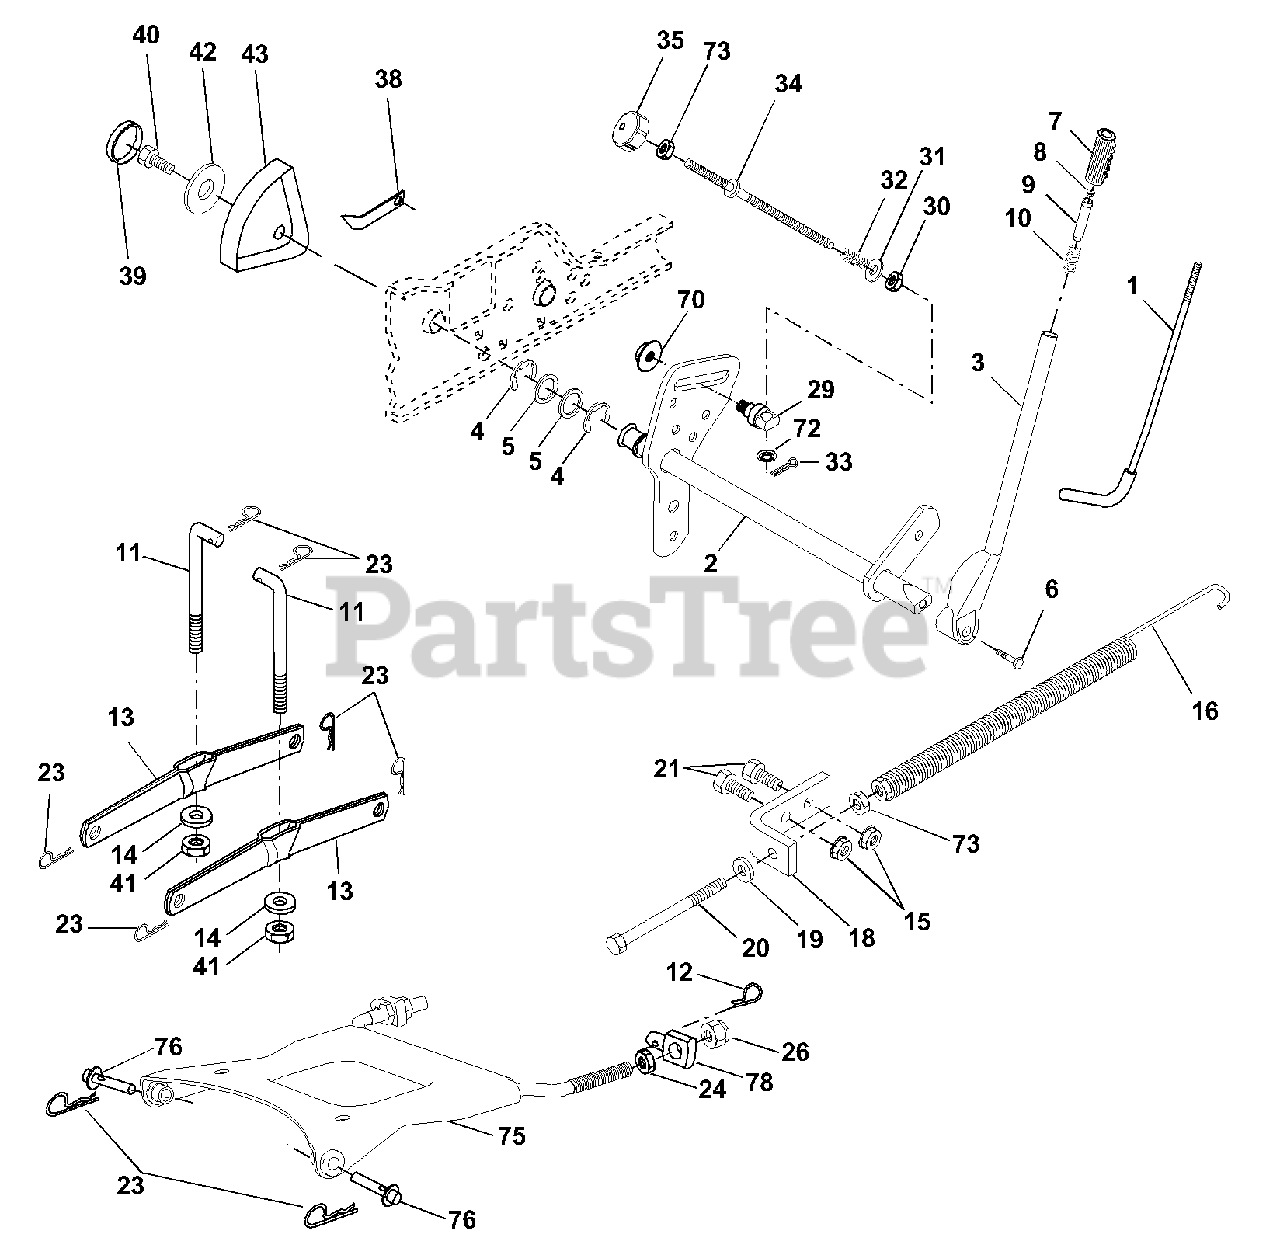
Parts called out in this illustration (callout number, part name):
1	Rod Asm., Lever
2	Shaft Asm., Lift Vgt
3	Lever Asm., Lift Rh
4	E-Ring Truarc #5133-87
5	Washer 29/32 x 1-1/4 x 16 Ga.
6	Bolt, Fin Hex 3/8-16 x 1-1/2
7	Grip, Handle
8	Button, Plunger
9	Plunger, Lever Lift
10	Spring 2-1/8"
11	Link Lift
12	Retainer, Spring
13	Arm, Suspension Vgt
15	Nut, Crownlock 3/8-16
16	Spring Asm., Assist Lift
18	Bracket, Spring Assist
19	Washer 13/32 x 13/16 x 16 Ga.
20	Bolt, Adjust Spring Assist
21	Bolt, Fin Hex 3/8-16 x 1
23	Retainer, Spring
24	Nut, Jam Hex 1/2-13 Unc
26	Nut, Lock W/Wsh 1/2-13 Unc
29	Trunnion Infin Height
30	Nut, Special
31	Washer 13/32 x 5/8 x 16 Ga.
32	Spring, Compression Inf Hgt
33	Pin, Cotter 3/32 x 1/2
34	Rod, Adj Lift
35	Knob, Inf 3/8-16 Unc
38	Pointer Height Indicator
39	Plug, Hole Blk. 1.485/1.515 Dia.
40	Screw 5/16-18 x 1
41	Nut, Crownlock 3/8-24
42	Washer 11/32 x 1-1/2 x 10 Ga.
43	Scale, Indicator Height
70	Nut Hex Flange Lock
72	Nut Push Phos & Oil
73	Nut, Hex Jam 3/8-16 Unc
75	Plate, Asm, Susp, Front
76	Pin Flange
78	Trunnion, Front, Susp
